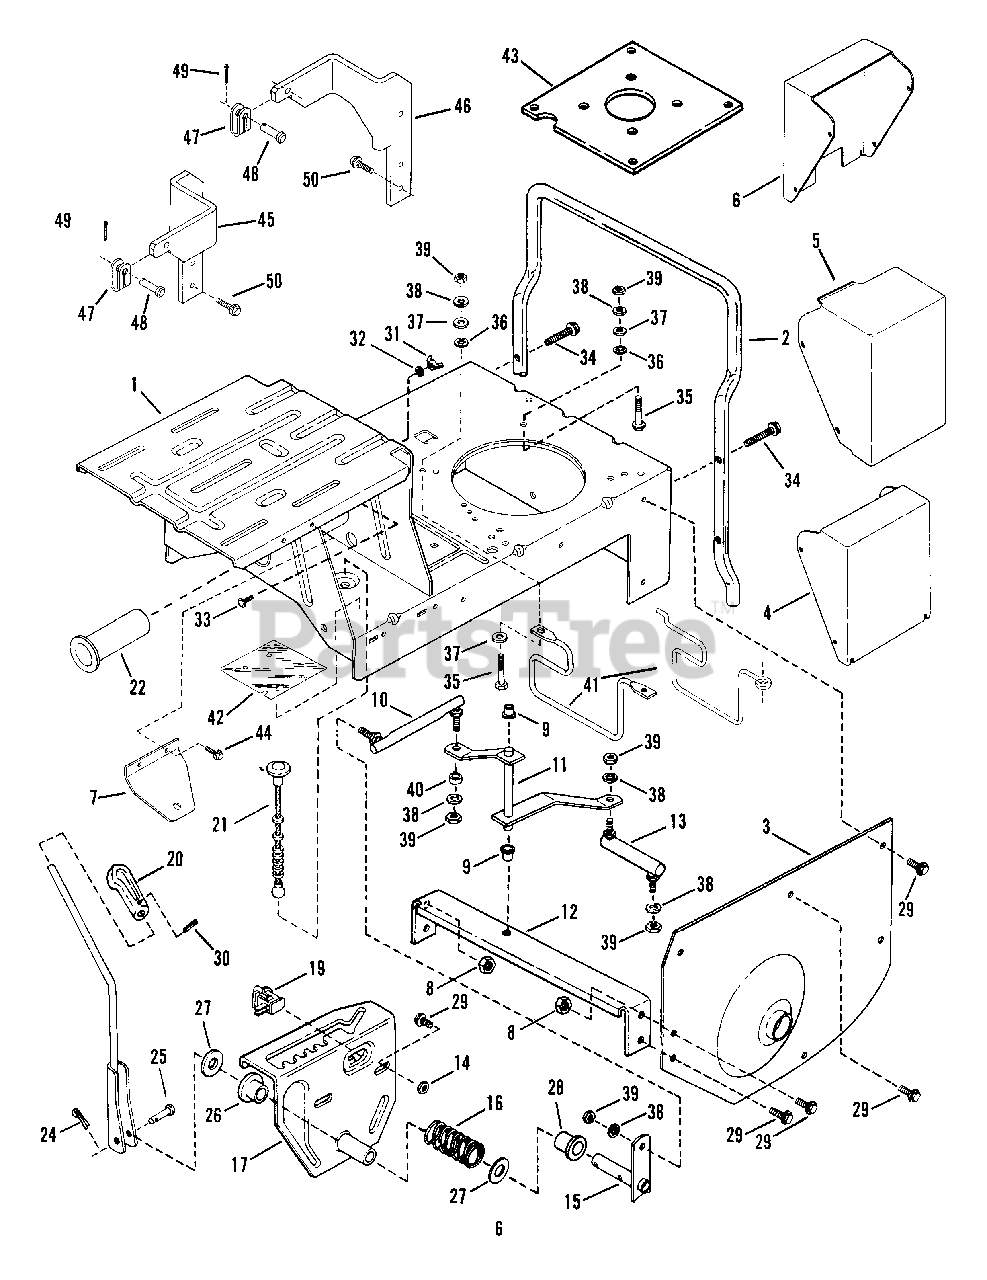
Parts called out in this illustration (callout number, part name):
1	CASE, Main (Standard)
2	BUMPER, Rear
3	FENDER, Left Hand
4	COVER
5	COVER, Battery
6	COVER, Switch
7	PLATE, Choke
8	NUT, 5/16-18 Hex Flange Lock
9	BUSHING, Nylon
10	LINK, Shift (Long)
11	ARM, Shift
12	BRACE, Cross
13	LINK, Shift (Short)
14	NUT, 5/16-18 Hex
15	ARM, Shift Handle
16	SPRING, Shift Handle
17	DETENT, Shift
19	SWITCH, Seat
20	KNOB, Shift Handle
21	CABLE, Deck Support
22	BUSHING, Pilot
24	PIN, 3/32 x 3/4" Cotter
25	PIN, 1/4 x 1-3/4" Tapered Clevis
26	BUSHING, Nylon
27	WASHER, Thrust
29	SCREW, 5/16-18 x 5/8" Self-Tapping
30	PIN, 3/16 x 3/4" Roll
31	NUT, #10-24 Locking Wing
32	RETAINER, #10 Bolt
33	FASTENER, 1/4 x 3/4" Ratchet
34	SCREW, 5/16-18 x 1-1/2" Self-Tapping
35	SCREW, 5/16-24 x 1-1/2" Hex Head Cap
36	RETAINER, 5/16 Bolt
37	WASHER, 5/16" Flat
38	WASHER, 5/16" Split Lock
39	NUT, 5/16-24 Hex
40	ROLLER
41	GUIDE, Belt
41	GUIOE, Belt
42	PROTECTOR, Solenoid
43	PLATE, Engine
44	SCREW, 1/4-20 x 5/8" Self-Tapping
45	DECK WING, Rear (Left)
46	DECK WING, Rear (Right)
47	BRACKET, Cable
48	PIN, 3/8 x 1 1/16" Clevis
49	PIN, 3/32 x 3/4" Cotter
50	SCREW, 5/16-18 x 1" Self-Tapping
